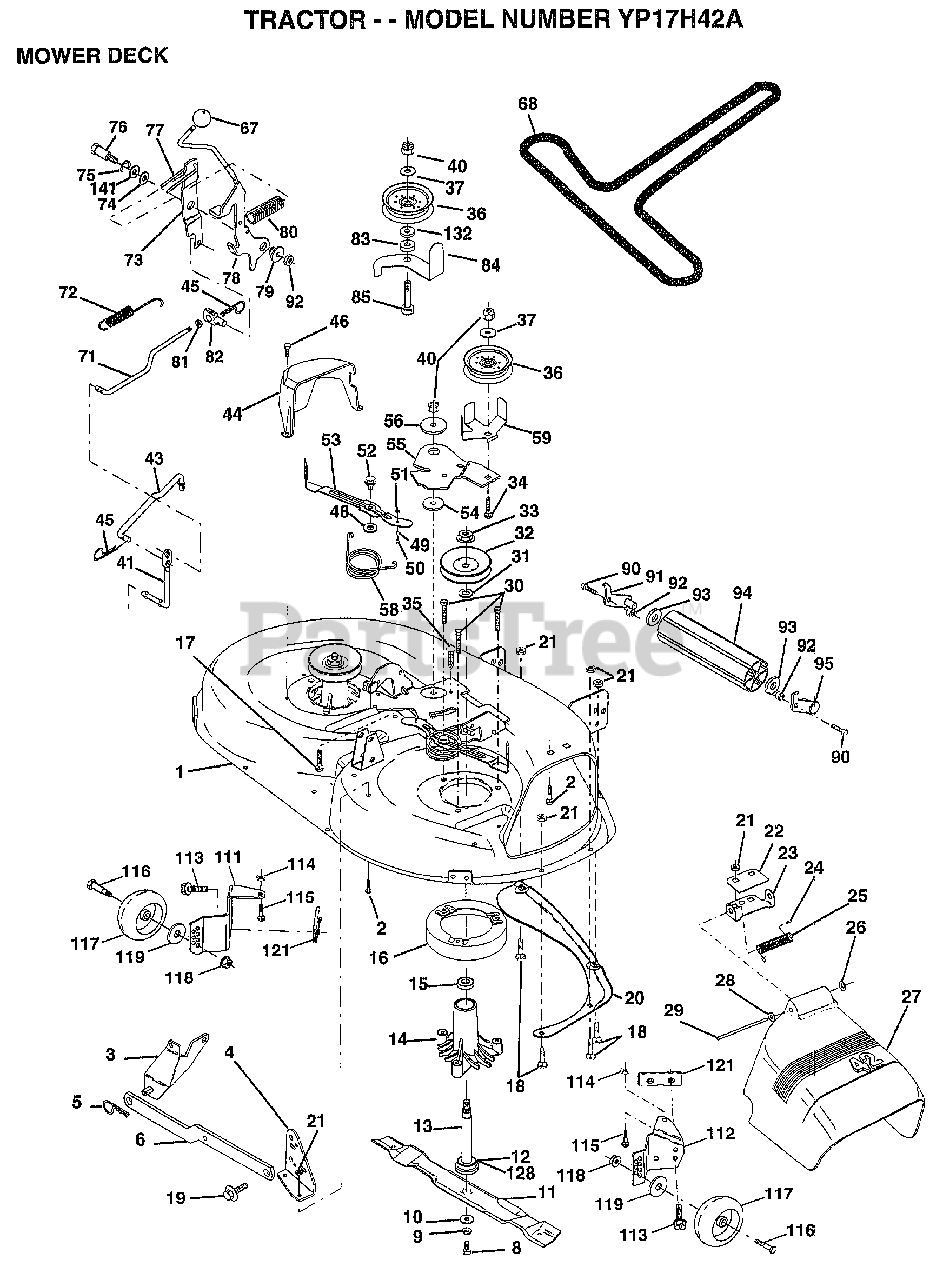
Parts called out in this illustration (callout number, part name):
1	"HOUSING ASSY.42"""
2	BOLT
3	BRKT ASM SWAY BAR
4	BRKT DECK SW BAR
8	BLADE BOLT
10	WASHER.HARD.BLADE
11	"BLADE.42"" HIPERF"
12	BEARING.BALL
14	HSG ASM MANDREL
15	BEARING
16	STRIPPER RND MWR
17	BOLT RDHD 3/8-16
18	BOLT
19	BOLT SHD 5/16-18
20	BAFFLE VORTEX 42
22	STIFFENER BRKT
23	DEFLECTOR BRKT
24	CAP-SLEEVE LT
25	SPRING TORSION
26	NUT PUSH M
27	DEFLECTOR.SHIELD
28	WASHER
29	HINGE ROD
30	"SCREW-THD ROLL,WA"
31	WASHER
32	PULLEY.MANDREL.42
34	BOLT
35	XMAS TREE FASTNER
36	FLAT IDLER PULLEY
37	WASHER
41	PIVOT ROD
43	ROD CLUTCH W/NIBS
44	GUARD MAND LH BLK
45	RETAINER M
46	SCREW.1/4-20X5/8
48	HARD SMALL WASHER
49	ROLLER ASM-CAM
50	SHOULDER BOLT
51	LOCKNUT
52	BOLT.SHLD.5/16-18
53	BRAKE PAD ARM ASM
54	HARDENED WASHER
55	ARM-IDLER
56	SPACER RETAINER
58	SPRING TORSN BRAK
59	GUARD IDLER TUV
67	KNOB.RD.7/16-14
68	BELT.V.T-PATH
71	ROD CLUTCH 38/42
72	RETURN SPRING
73	CLUTCH ARM SECOND
74	WASHER
75	RING
76	SHOULDER BOLT
77	SPRING KEEPER
78	LEVER.ASM.CLUTCH
79	BUSHING
80	SPRING.CLUTCH.MWR
81	NUT
82	TRUNION ADJ
83	WASHER
84	"KEEPER-BELT,FIXED"
85	BOLT
90	BOLT
92	NUT
93	WASHER
111	BRACKET.GWHL.LH.
112	BRACKET.GWHL.RH.
113	SCREW
116	BOLT M
117	WHEEL.GUAGE
118	LOCKNUT
119	WASHER
121	BRACKET.EXTRD.GWL
128	WASHER.FELT.
132	WASHER GT
141	WASHER .T
